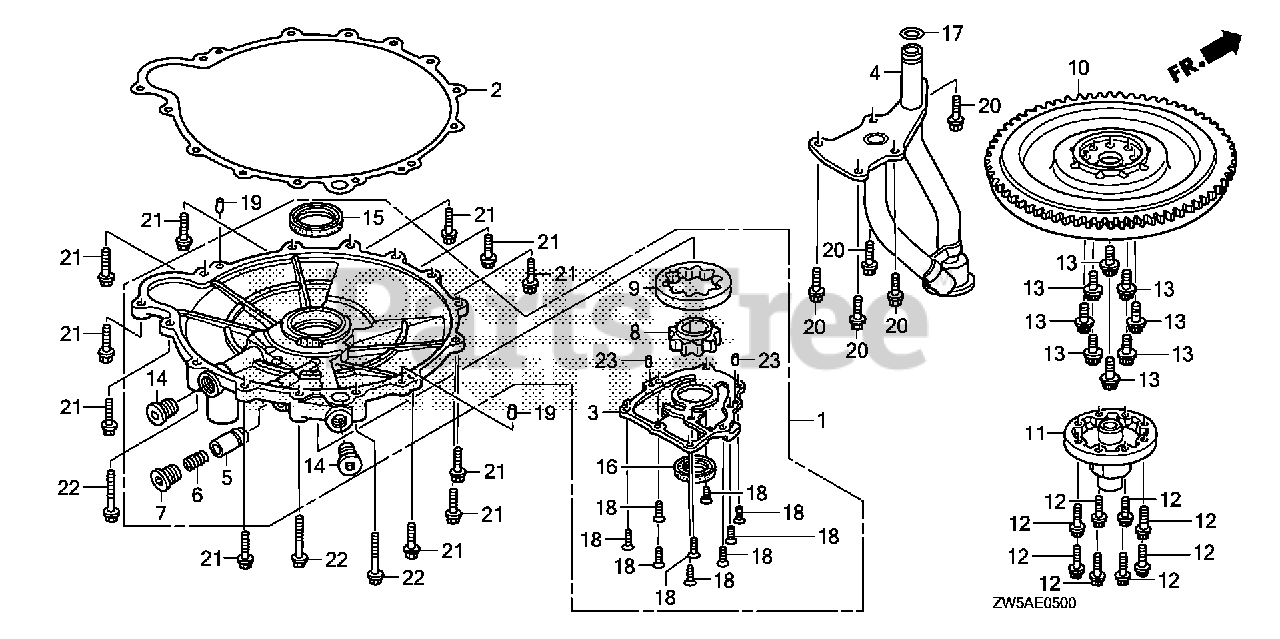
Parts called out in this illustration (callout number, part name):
1	PUMP ASSY., OIL
2	GASKET, OIL PUMP BODY
3	COVER, OIL PUMP
4	STRAINER, OIL
5	VALVE, RELIEF
6	SPRING, RELIEF VALVE
7	BOLT, SEALING (18MM)
8	ROTOR, OIL PUMP (INNER)
9	ROTOR, OIL PUMP (OUTER)
10	FLYWHEEL *TBLACK* (BLACK)
11	BOSS, FLYWHEEL
12	BOLT, SPECIAL (8MM)
13	BOLT (12MM)
14	BOLT, SEALING (22MM) (NOT AVAILABLE)
14	BOLT, SEALING (22MM)
15	OIL SEAL (46X60X9)
16	OIL SEAL (31X46X7) (NOK)
17	O-RING (20.6X2.6)
18	SCREW, FLAT (6X16)
19	PIN, DOWEL (6X10)
20	BOLT, FLANGE (8X20)
21	BOLT, FLANGE (8X30)
22	BOLT, FLANGE (8X50)
23	ROLLER (5X8)
